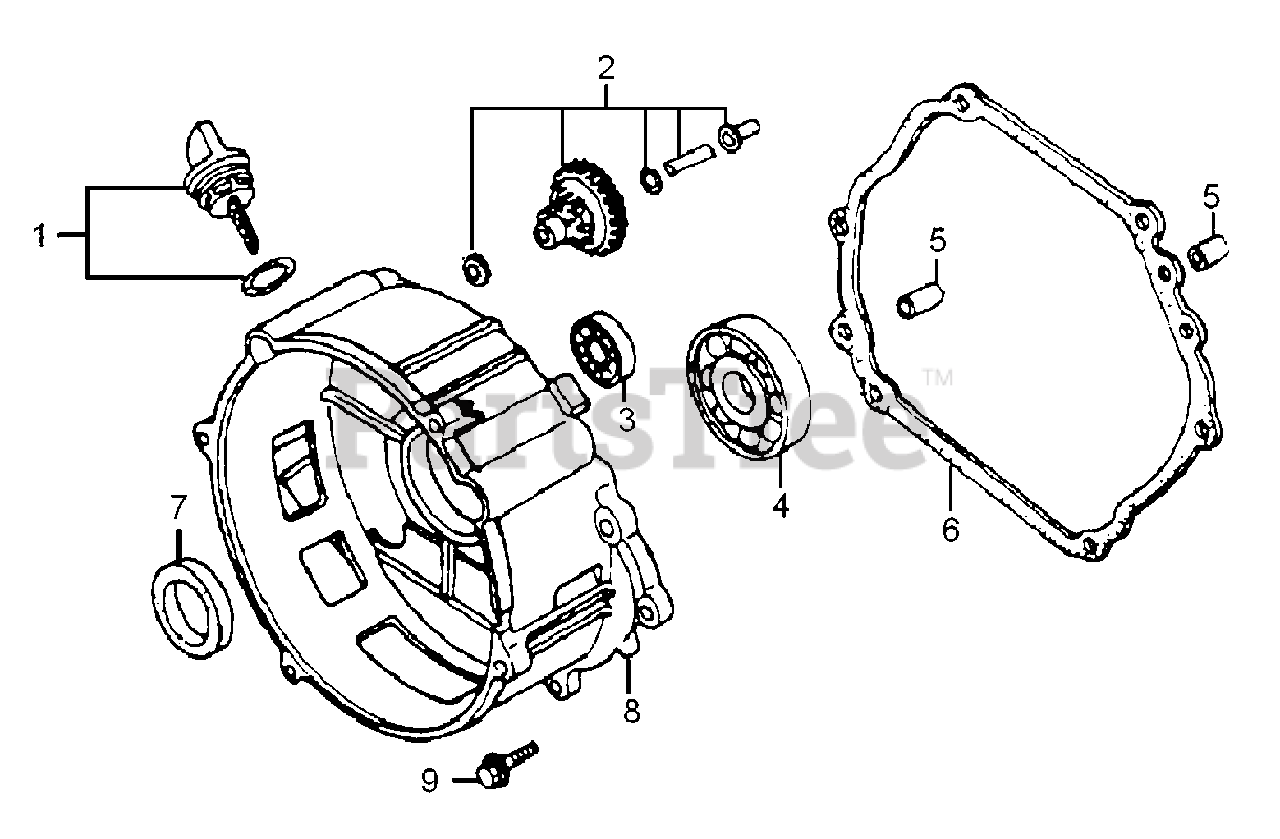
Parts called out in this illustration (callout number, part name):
1	OIL DIPSTICK W/ O-RING (ORANGE)
2	GOVERNOR ASSY
3	BEARING, RADIAL BALL 6202
4	BEARING, RADIAL BALL 6207
5	PIN, DOWEL 8X12
6	GASKET, CASE COVER
7	OIL SEAL 35X52X7
8	COVER, CRANKCASE
9	BOLT, FLANGE M8X40
